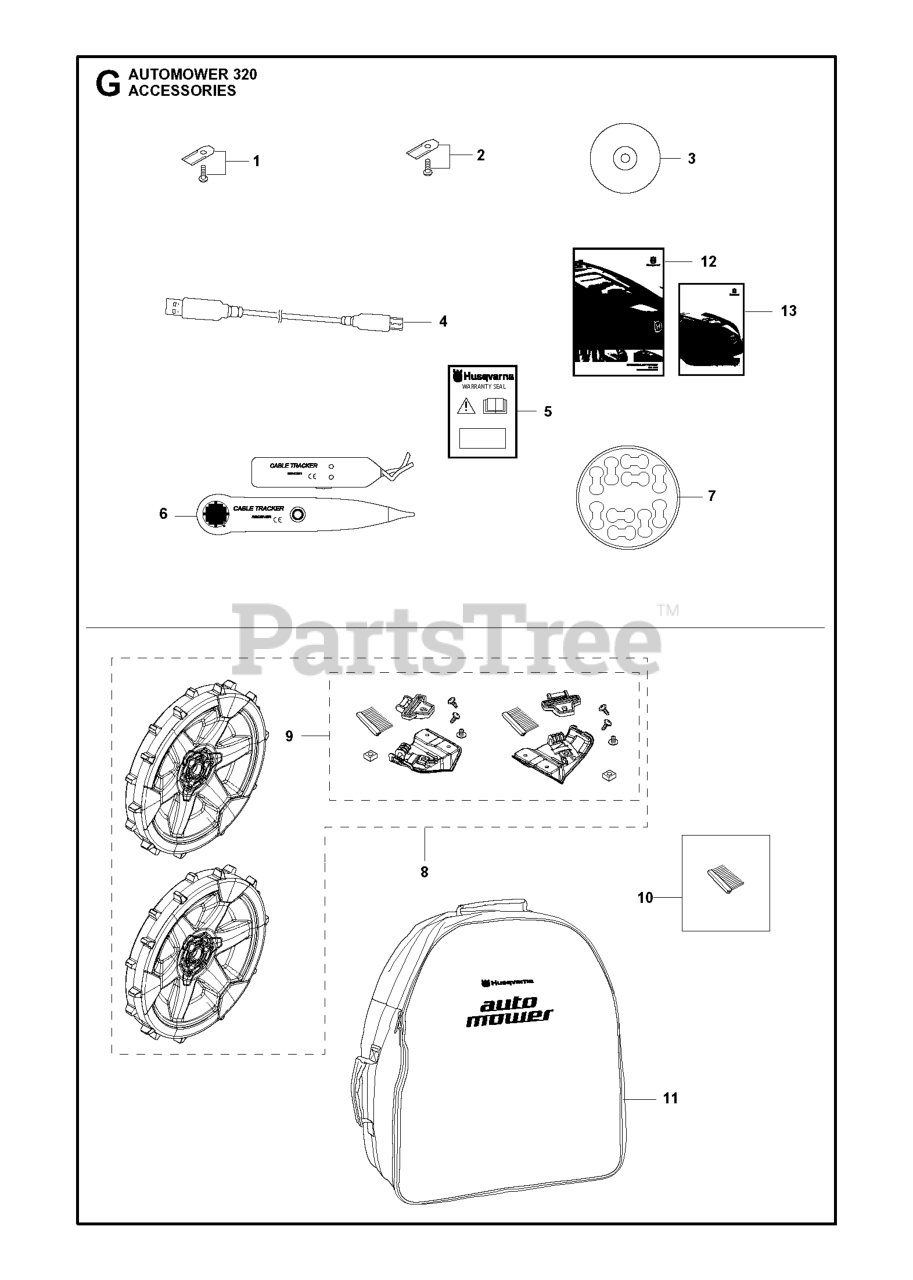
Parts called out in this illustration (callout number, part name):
1	BLADE
1	BLADE - BULK PACK 500 PCS
1	BLADE - 30 PCS
1	BLADE KIT
2	BLADE CARBON STEEL, THICK BLAD
2	BLADE 300PCS -SINGLE HOLE THIC
2	BLADE 9PCS EXTRA THICK
2	BLADE BLADE KIT INCL PACKAGING
5	LABEL WARRANTY SEAL DEALER
5	LABEL WARRANTY SEAL KIT 10 PK
6	TEST EQUIPMENT
